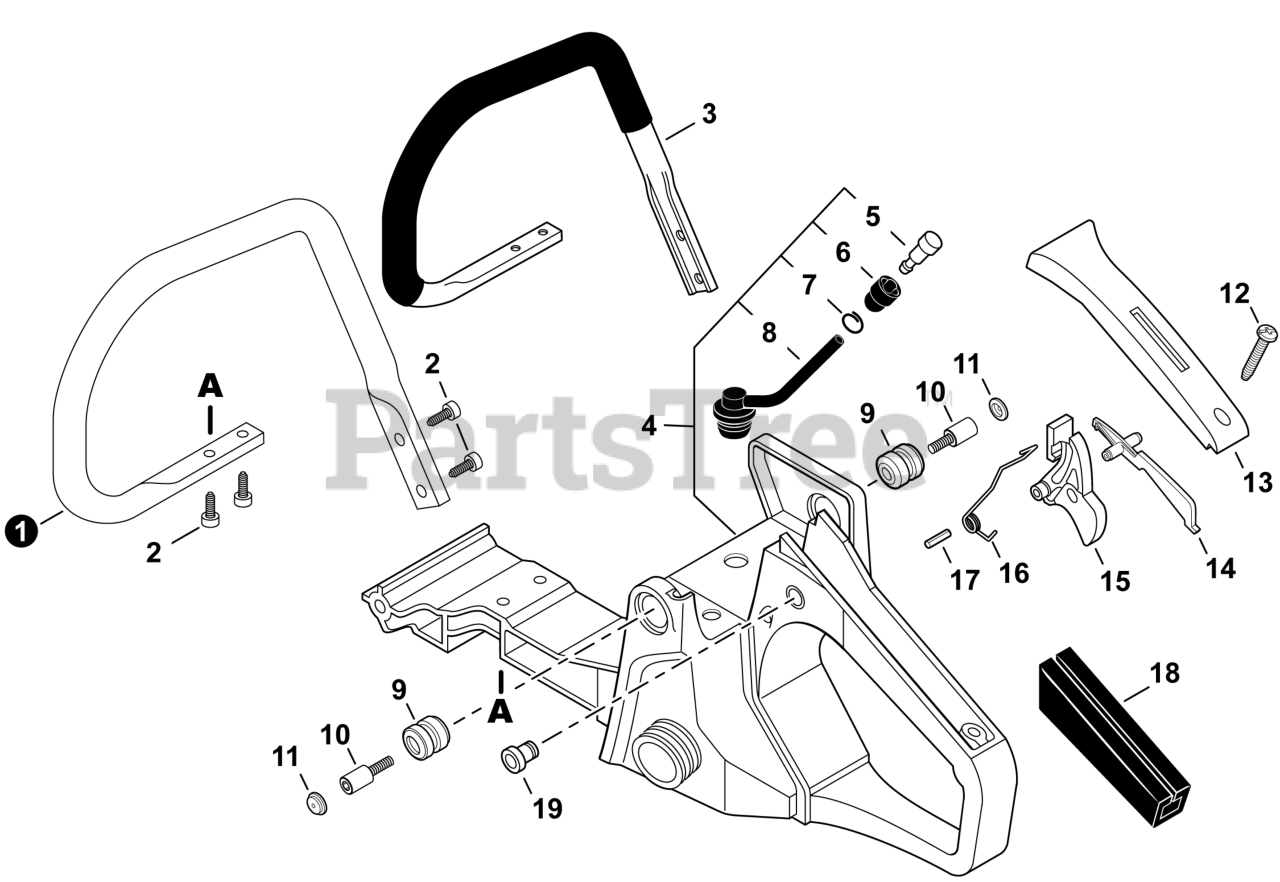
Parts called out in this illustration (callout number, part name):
1	HANDLE, FRONT
2	BOLT 5x20
3	HANDLE, FRONT - ALUMINUM
4	HANDLE ASSY, REAR
5	VENT ASSY
6	HOLDER, VENT
7	CLIP 6.5 MM
8	PIPE, VENT 3x6x65
9	CUSHION 4
10	BOLT 4x10x13.5
11	CAP, CUSHION
12	SCREW 4x14
13	COVER, HANDLE
14	LOCKOUT, THROTTLE
15	TRIGGER, THROTTLE
16	SPRING, TORSION
17	PIN, SPRING 4x30
18	GRIP, HANDLE
